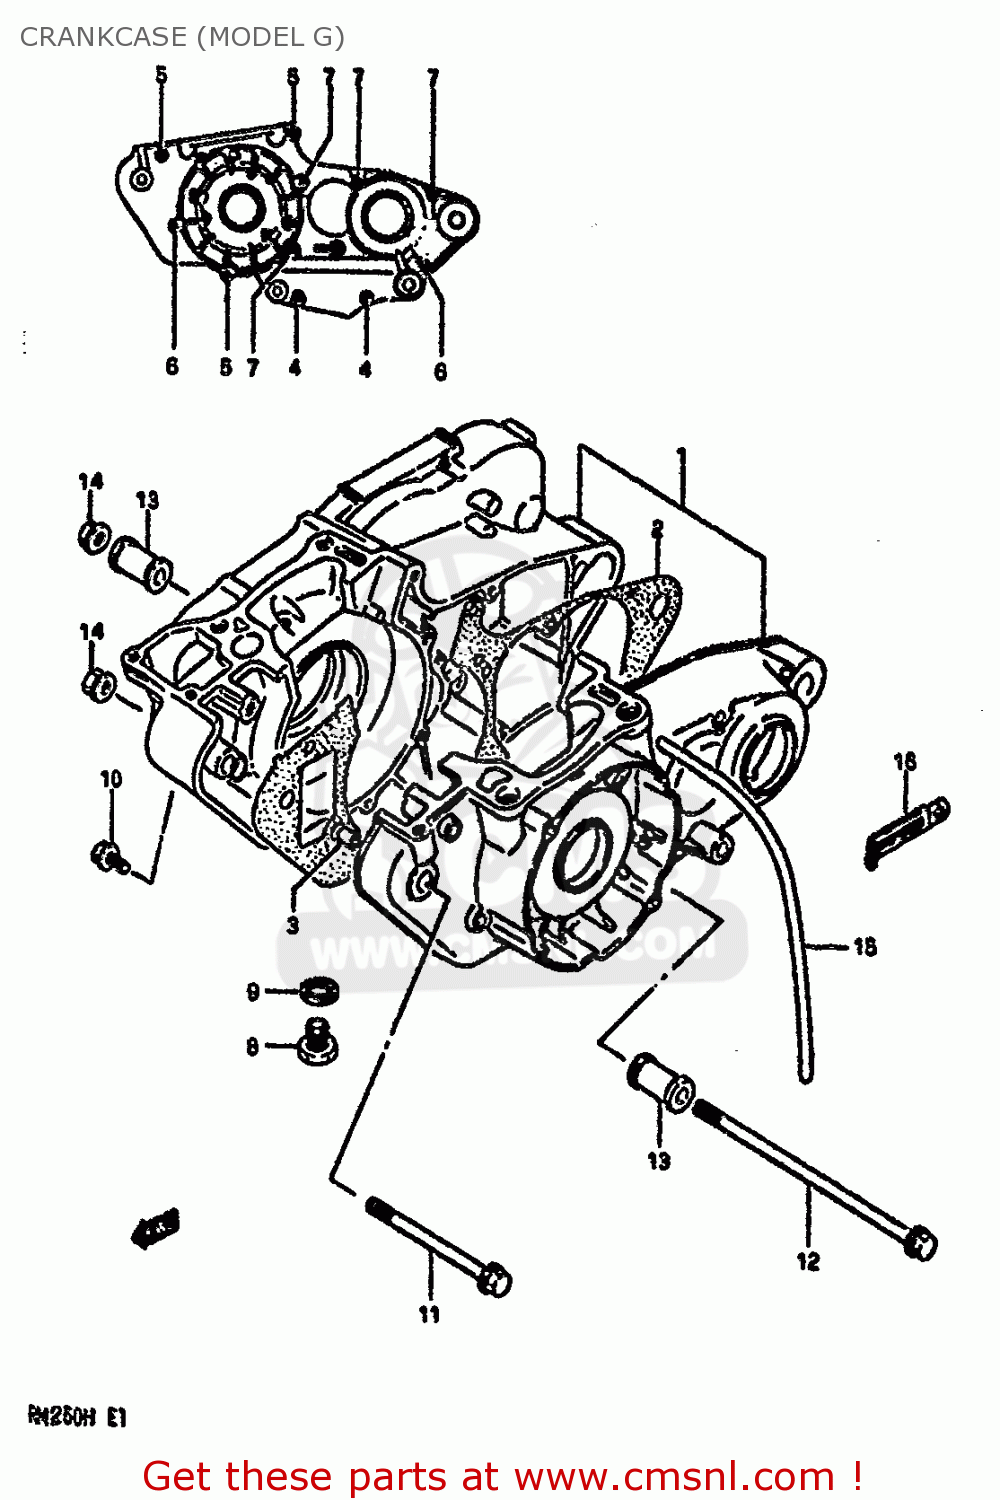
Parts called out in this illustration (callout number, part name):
1	CRANKCASE SET
2	GASKET,CRANKCASE (MCA)
3	PIN
4	SCREW (6X35)
5	SCREW (6X45)
6	SCREW
7	SCREW 6X60
8	PLUG
9	GASKET(14X19.2X2) (NAS)
10	SCREW (6X10)
11	BOLT(8X100)
12	BOLT
13	SPACER,ENGINE MOUNT(L:32)
14	NUT
15	HOSE
16	CLAMP
